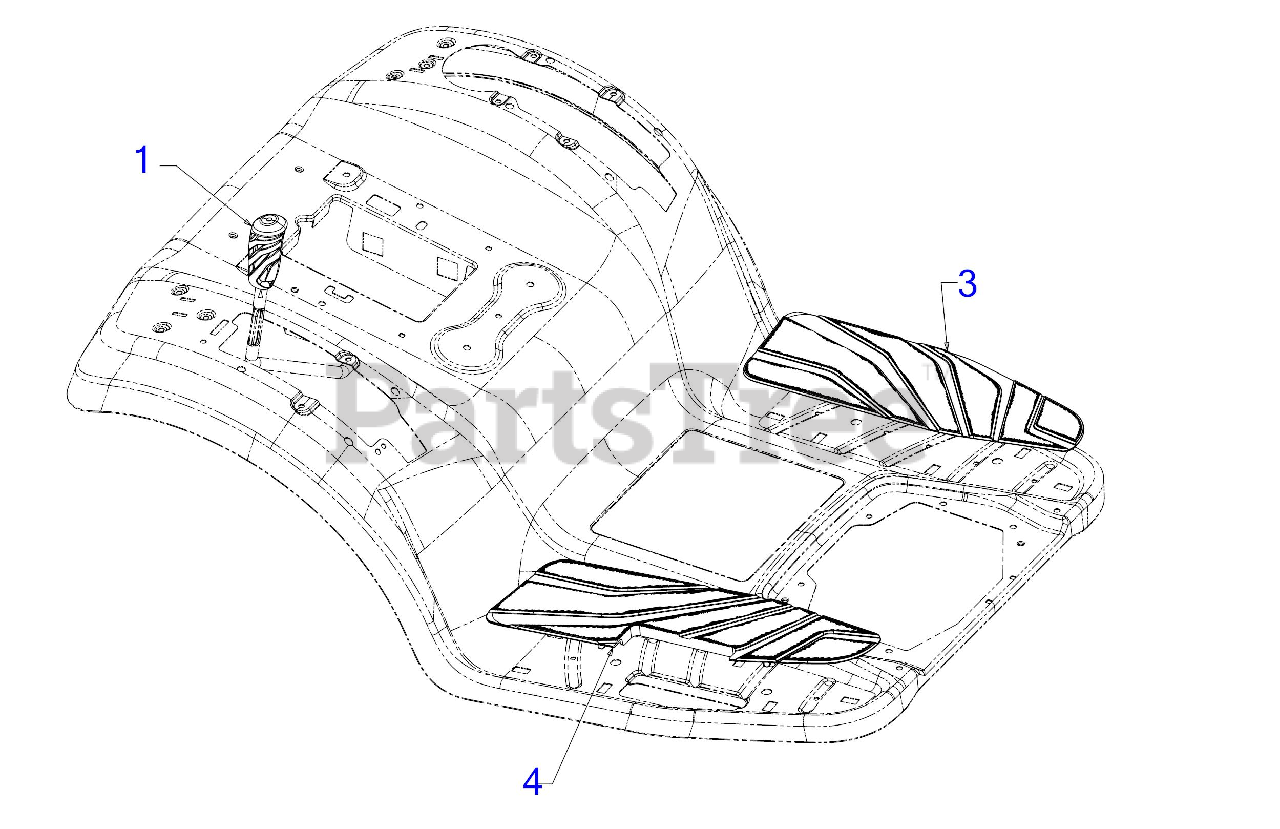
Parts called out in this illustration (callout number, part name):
1	LIFT HANDLE GRIP .542 ID
3	FOOTPAD (LH)
4	FOOTPAD (RH)
